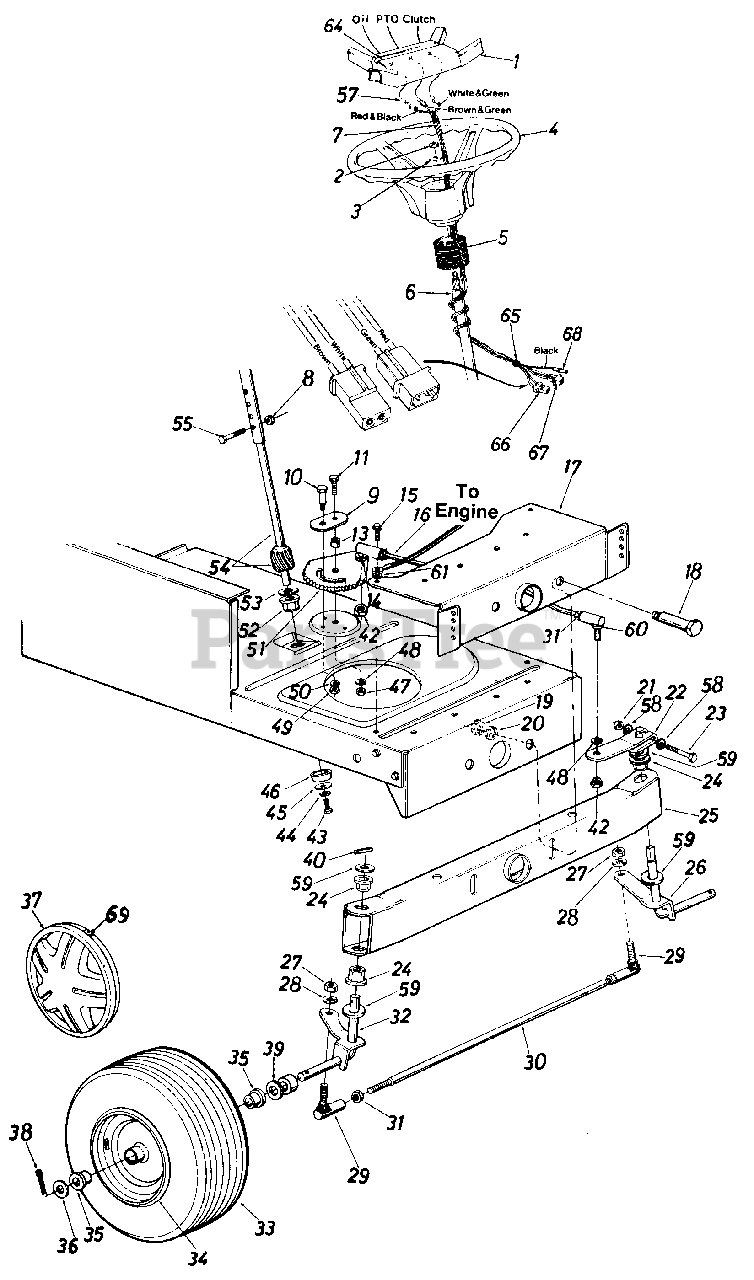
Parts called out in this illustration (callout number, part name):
1	Steering Wheel Insert
2	Hex L-Nut 5/16-24 Thd.
3	Belleville Wash. .345" I.D.
4	Steering Wheel
5	Steering Bellow
6	Steering Column Ass'y.
7	Harness Indicator Lights
8	Hex L-Nut 1/4-20 Thd.
9	Retainer Plate
10	Shoulder Bolt .437" Dia. x .35" Lg. 5/16-18 Thd.
11	Hex Bolt 3/8-24 x 1.0" Lg. (Grade 5)
13	Spacer .380" I.D. x .625" O.D. x .227"
14	L-Wash. 3/8" I.D.
15	Hex Wash. Hd. Self-Tap Scr.
16	Steering Drag Link
17	Front Pivot Brkt.
18	Shoulder Bolt .498" Dia. x 2.04" Lg. 3/8-16 Thd.
19	Hex Nut 3/8-16 Thd.
20	L-Wash. 3/8" I.D.
21	Hex Cent. L-Nut 5/16-24 Thd.
22	Steering Arm Front Axle
23	Hex Bolt 5/16-24 x 2.00" Lg. (Grade 5)
24	Hex Flg. Brg. .634" I.D.
26	Front Axle Ass'y.-L. H .
27	Hex Nut 3/8-24 Thd.
28	L-Wash. 3/8" I.D.*
29	Ball Joint 3/8-24 Thd.
30	Tie Rod
31	Hex Jam Nut 3/8-24 Thd.
32	Front Axle Ass'y.-R.H.
33	Wheel Ass'y. Comp.
34	Front Wheel Rim Only
35	Needle Bearing
36	Fl-Wash. .635" I.D. x 1.59 O.D.
37	Hub Cap
38	Cotter Pin 1/8" Dia. x 1.25" Lg.
39	Fl-Wash. .640" I.D. x .24" O.D.
40	Spring Roll Pin
42	Hex Jam Nut 3/8-24 Thd.
43	Hex L-Bolt 5/16-18 x .62"
44	L-Wash. 5/16" I.D.
45	Fl-Wash. .33" I.D. x 1.25" O.D.
46	Spacer (Plastic)
47	Hex Nut 3/8-24 Thd.
48	L-Wash. 3/8" I.D.
49	Hex Nut 5/16-18 Thd.
50	L-Wash. 5/16" I.D.
51	Steering Gear Segment
52	Hex Flg. Brg. .634 I.D.
53	Fl-Wash. (Hardened)
54	Steering Shaft Lower
55	Hex Bolt 1/4-20 x 1.31" Lg.
57	Bulb
58	Wave Wash. .32" I.D. x .62n
59	Fl-Wash. (Hardened)
60	Drag Link Ball Joint 3/8-24 Thd.
61	Ext. L-Wash. 5/16" I.D.
64	Steering Wheel Insert Label
65	Clamp
66	Connector
67	Connector
68	Connector
69	Mounting Clip
